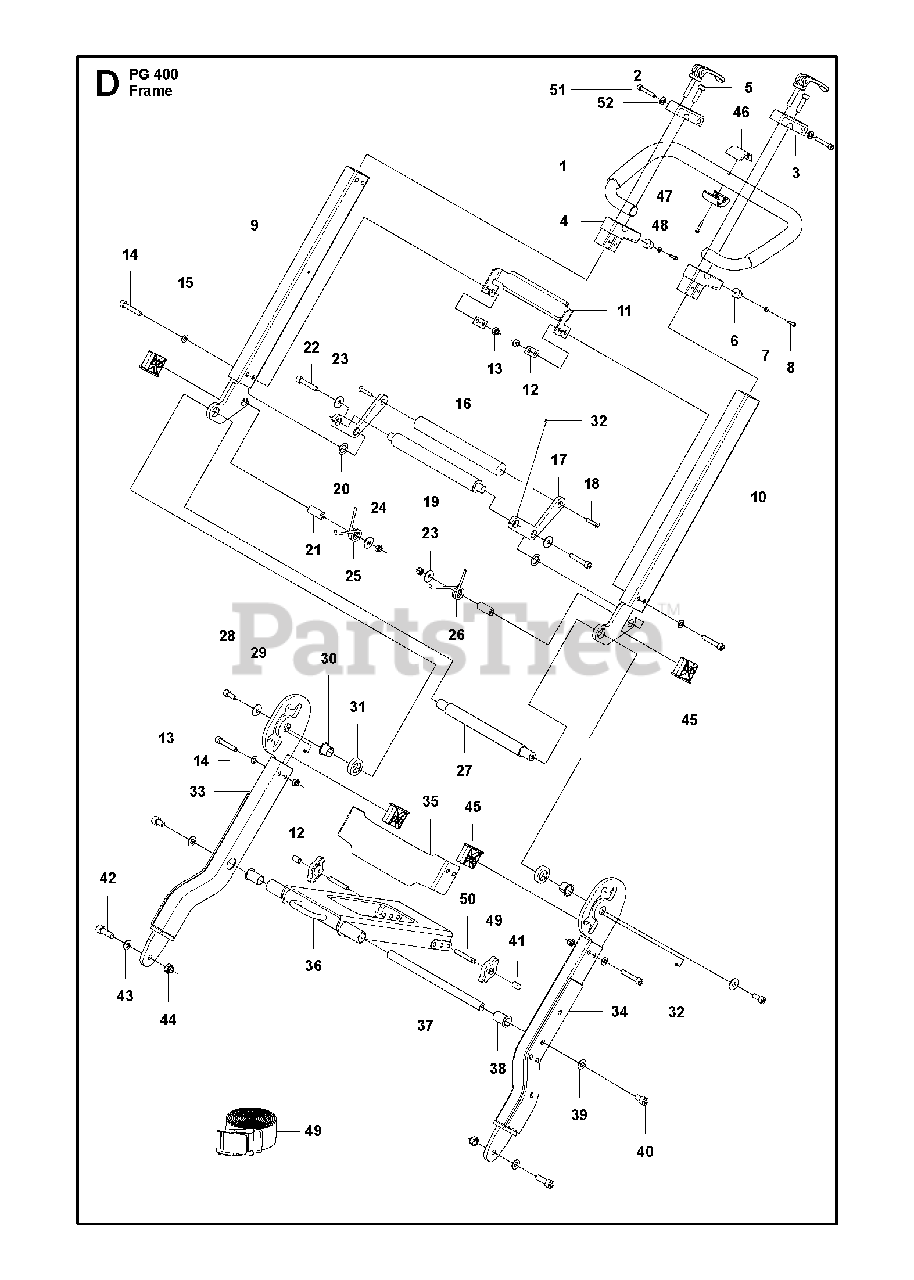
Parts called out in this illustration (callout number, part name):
13	HEXAGON LOCKING NUT
15	WASHER
24	HEXAGON LOCKING NUT
32	SCREW IHSETM
35	BRACKETHDX variant only
36	SUPPORT
39	WASHER
43	WASHER
44	HEXAGON LOCKING NUT
52	WASHER
